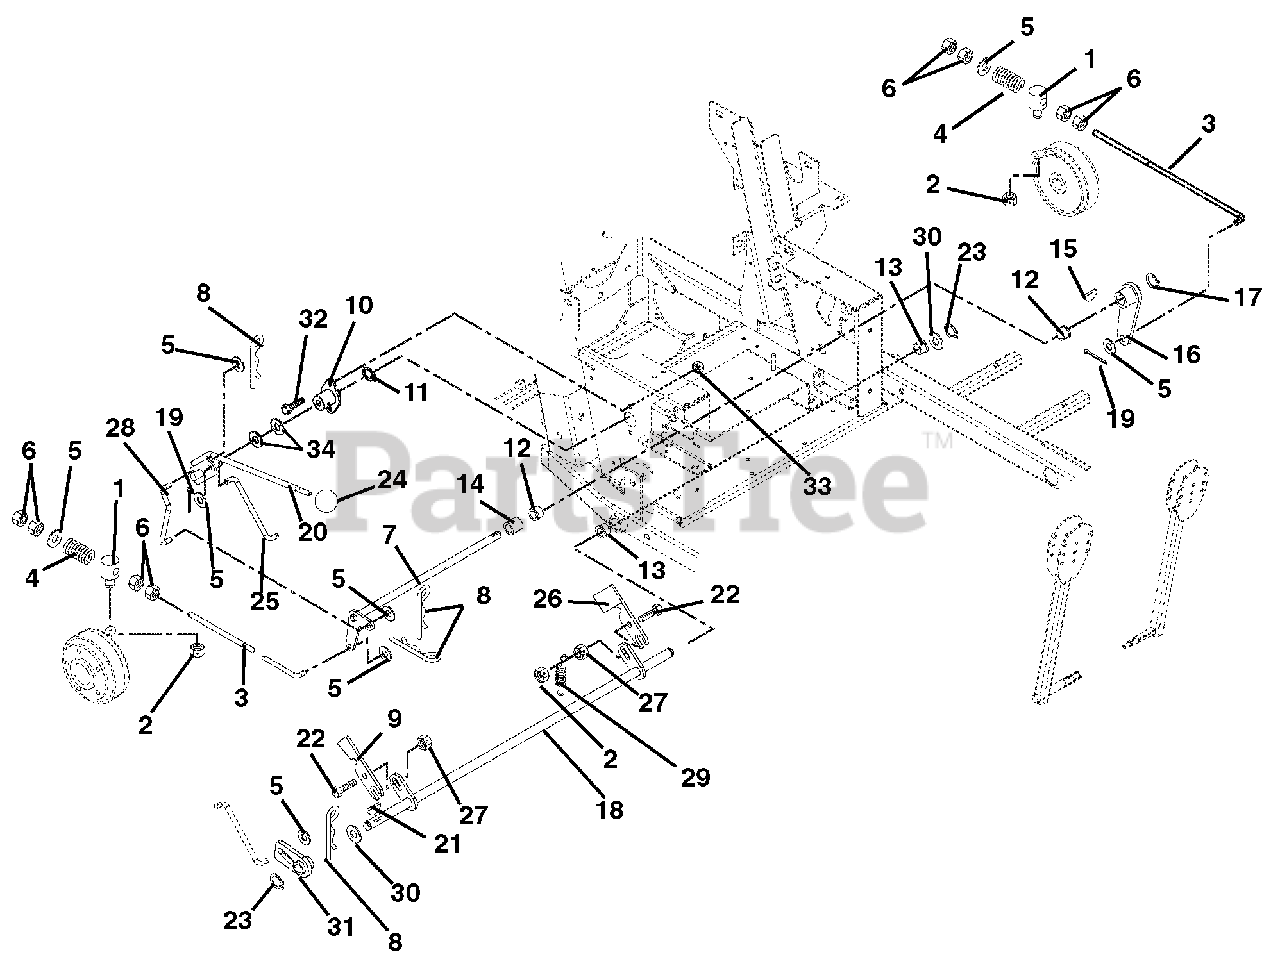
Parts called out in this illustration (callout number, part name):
1	PIN, PIVOT/TRUNNION
2	@NUT-LK-CTR .31-18 YWZC
3	PTO LINK ROD, PRO-150
4	SG-COMP .142 X .710 X 1.75
5	@WSHR-FL-STL.406X.812X.065 YWZ
6	@NUT-HEX .38-16 YWZC
7	WMT, BRAKE CROSS SHAFT
8	PIN-HAIR, ENDRIES #25 YWZC
9	SLIDE, INTERLOCKING BRAKE
10	BUSHING, FLANGED
11	RG-RTNG-EXT .625X.050
12	BSHG-FLG .762X1.0X.580X1.48 NY
13	BSHG-FLG .515X.750X.745X1.00NY
14	BSHG-SLV .750X1.000X.750
15	KEY-WDRF .19X.75 HRD #9
16	WMT, BRAKE ARM
17	RG-RTNG-EXT .689X.078
18	WMT, MECHANICAL BRAKE
19	@PIN-CTR .09X.75 EXTPRSQCT YWZ
20	WMT, BRAKE HANDLE
21	KEY-WDRF .13X.63 HRD#5
22	@BLT-RDHDSQNK .31-18X1.25 G5YZ
23	RG-RTNG-EXT .500X.050 (SNAP)
24	GRIP,HANDLE
25	LINKAGE, BRAKE ACTUATING
26	INTERLOCK, SAFETY SWITCH
27	@NUT-LK-TOP-FLG .31-18 YWZC
28	LINKAGE, BRAKE ACTUATING
29	SG-TENS .063X.44X1.56
30	WSHR-FL-STL .505X1.00X.062YWZC
31	WMT, PARKING BRAKE HUB
32	@BLT-HEX .31-18X.75 GR5 YWZC
33	@NUT-LK-TOP-FLG .31-18 YWZC
34	WSHR-FL-STL .630X1.250X.062 YZ
